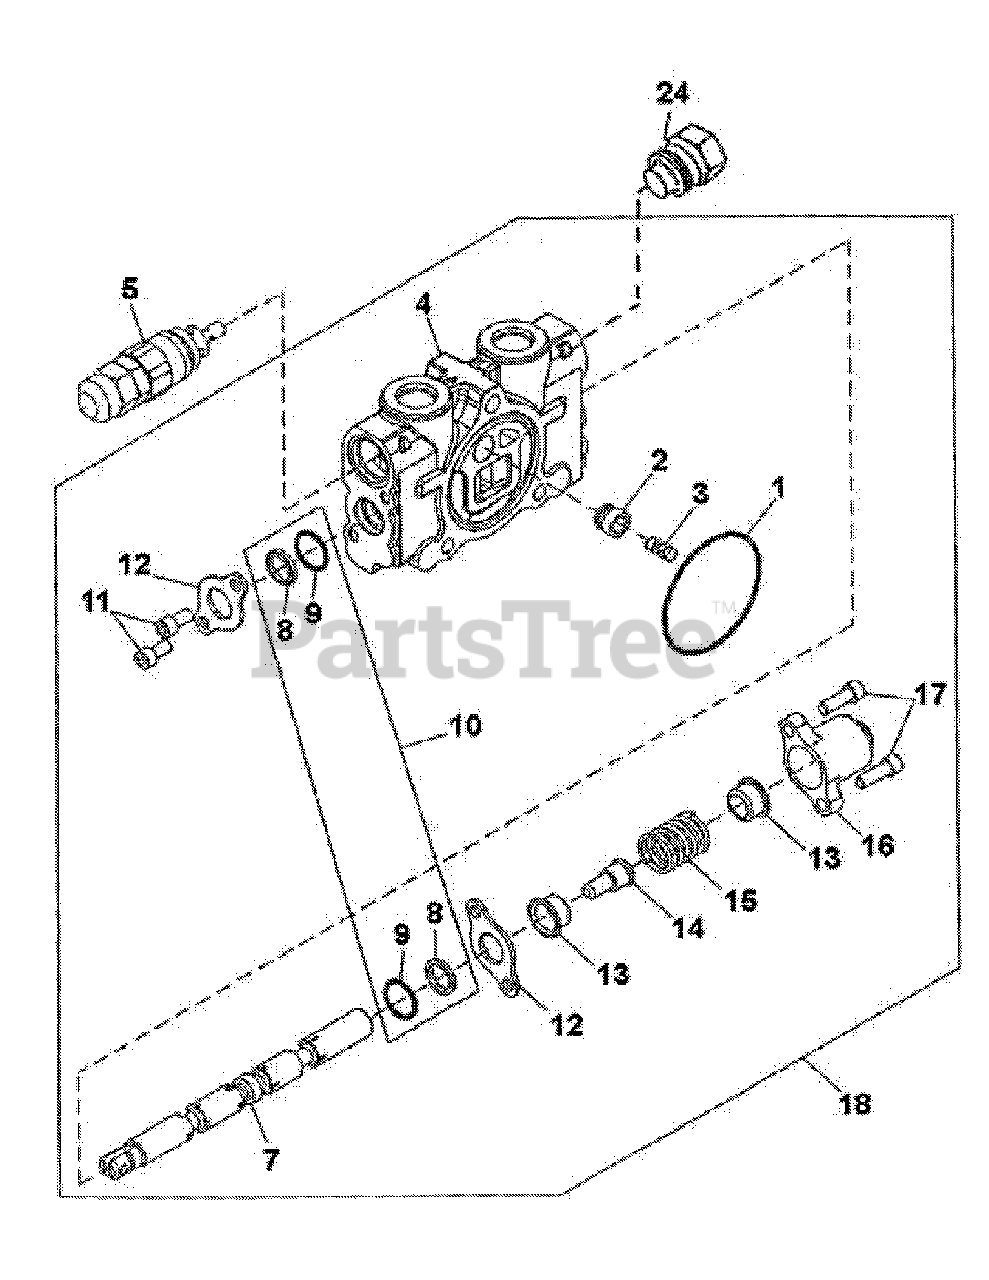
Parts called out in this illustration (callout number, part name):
1	O-Ring
2	Poppet, Load Check
3	Spring, Load Check
4	Valve Section
5	Relief, Work Port 2800 psi
7	Spool
8	Wiper, Spool
9	O-Ring, Spool
10	Seal Kit, Minor (contains two of Item 8 & 9)
11	Cap Screws, Socket Head
12	Plate, Retainer
13	Seat, Spring
14	Screw, Spring Seat
15	Spring, Spool Centering
16	Cap, Spring Spool
17	Cap Screws, Socket Head
18	Valve Section Assembly (less Item 5 & 24)
19	Seal Kit, Major
20	Load Check Poppet Kit
21	Spring Centered Spool Positioner Kit
22	Seal Kit, Work Port Relief
23	Spring & Seal Kit, Work Port Relief
24	Plug, Shut Off
